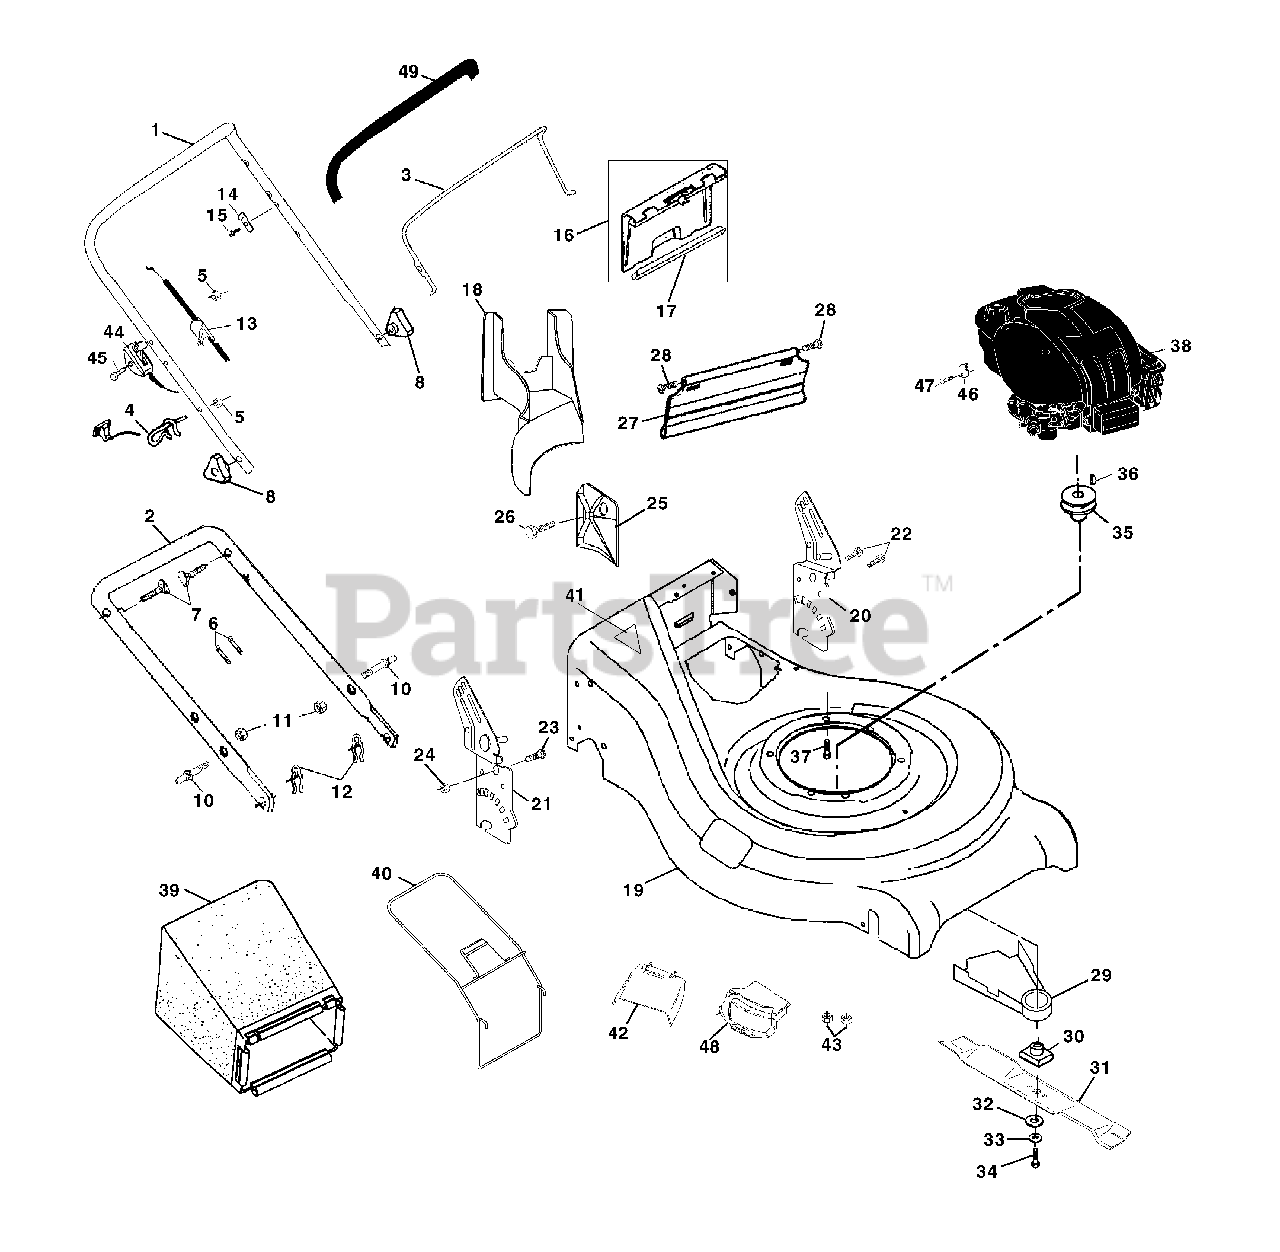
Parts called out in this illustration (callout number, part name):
1	Handle, Upper Dlx Comf.
2	Handle, Lower
3	Bail, Cont. Wire Dlx Comf. Blk
4	Guide, Rope, Side
5	Nut, Hex Lockwasher 1/4-20
6	Wire, Tie
7	Bolt, Handle 5/16-18 x 1.75
8	Knob, Handle
10	Bolt, Sq. Neck
11	Nut, Hex Lockwasher Ins. 5/16-18 UNC
12	Cotter, Hairpin
14	Bracket, Upstop
15	Screw, Hex Washer Head Tapping 10-2
16	Kit, Door Rear
17	Seal, Door
18	Plug, Mulcher
19	Kit, Housing
20	Handle, Bracket Asm. Left
21	Handle, Bracket Asm. Right
22	Screw, Hex Wshd
23	Bolt, Hex Head 5/16-18 x 5/8
24	Nut, Hex Lock Wshr 5/16-18
25	Baffle, Side
27	Skirt
28	Screw, Hinge 1/4-20 x 1.25
29	Shield, Debris Modified
30	Adapter, Blade w/key Longer
31	Blade, 21"
32	Washer, Hardened
33	Lockwasher, Helical Spring 3/8
34	Screw, Hex Head 3/8-24 x 1.38
35	Pulley, Engine
36	Key, Hi Pro
37	Bolt, Engine
38	Engine Briggs & Stratton
39	Grass Catcher Bag
40	Grass Catcher Frame
41	Danger Decal
42	Deflector
44	Throttle Control
45	Screw
46	Cable Clamp
48	Mulcher Door
49	Grip
